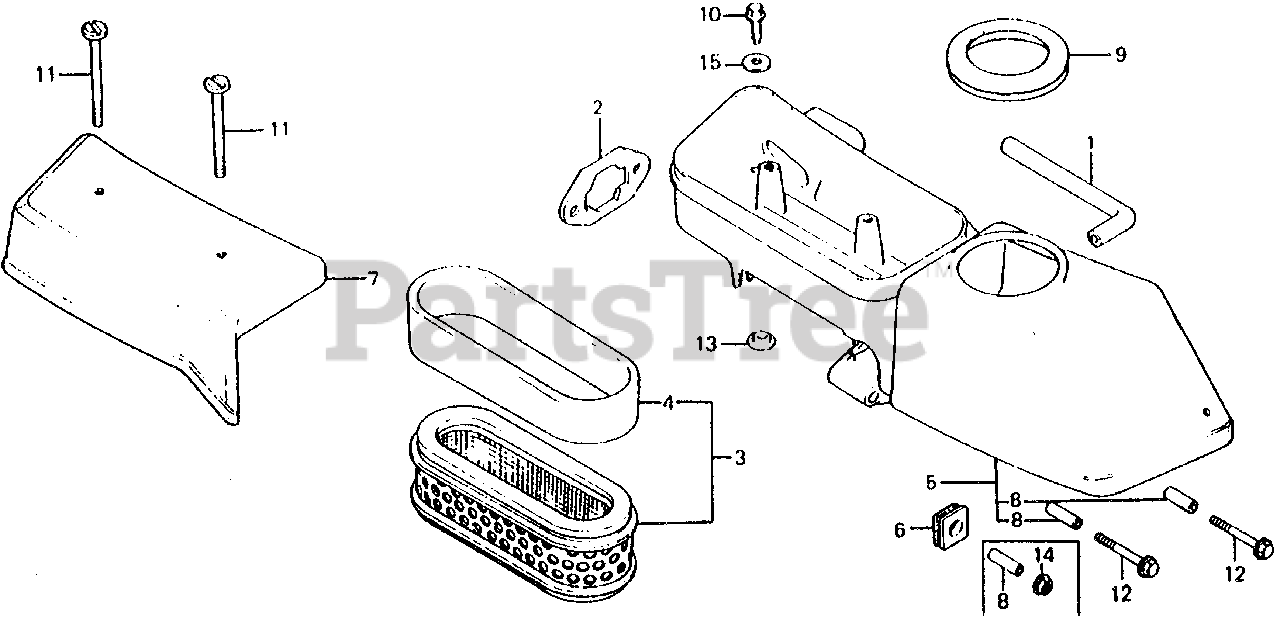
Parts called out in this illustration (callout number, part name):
1	TUBE, BREATHER (NOT AVAILABLE)
2	GASKET, AIR CLEANER
3	ELEMENT, AIR CLEANER
4	FILTER (OUTER)
5	HOUSING, AIR CLEANER (NOT AVAILABLE)
6	GROMMET, AIR CLEANER HOUSING
7	COVER, AIR CLEANER
8	COLLAR, AIR CLEANER (NOT AVAILABLE)
9	SEAL, FILLER NECK
10	BOLT, FLANGE (5X16)
11	BOLT, AIR CLEANER COVER
11	BOLT, AIR CLEANER COVER (NOT AVAILABLE)
12	BOLT, FLANGE (5X83)
13	COLLAR, GEARSHIFT LEVER SETTING
14	NUT, FLANGE (5MM)
15	WASHER, PLAIN (5MM)
